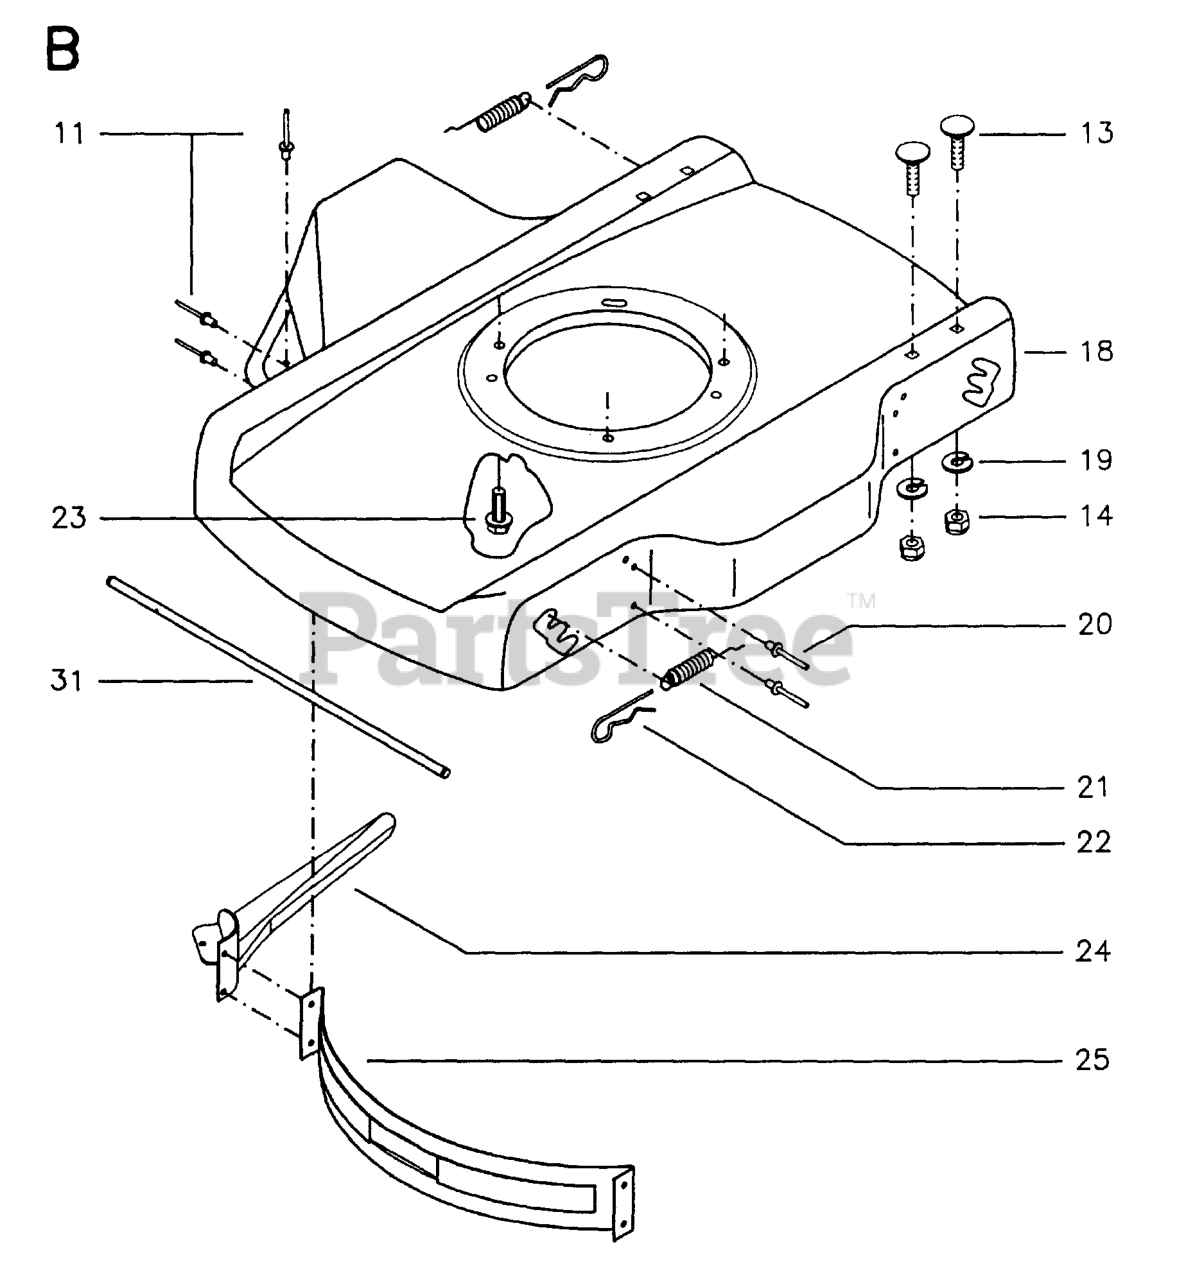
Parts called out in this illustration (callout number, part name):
11	REPL BY 516 92 38-00
14	NUT
19	SPRING WASHER
20	RIVET
